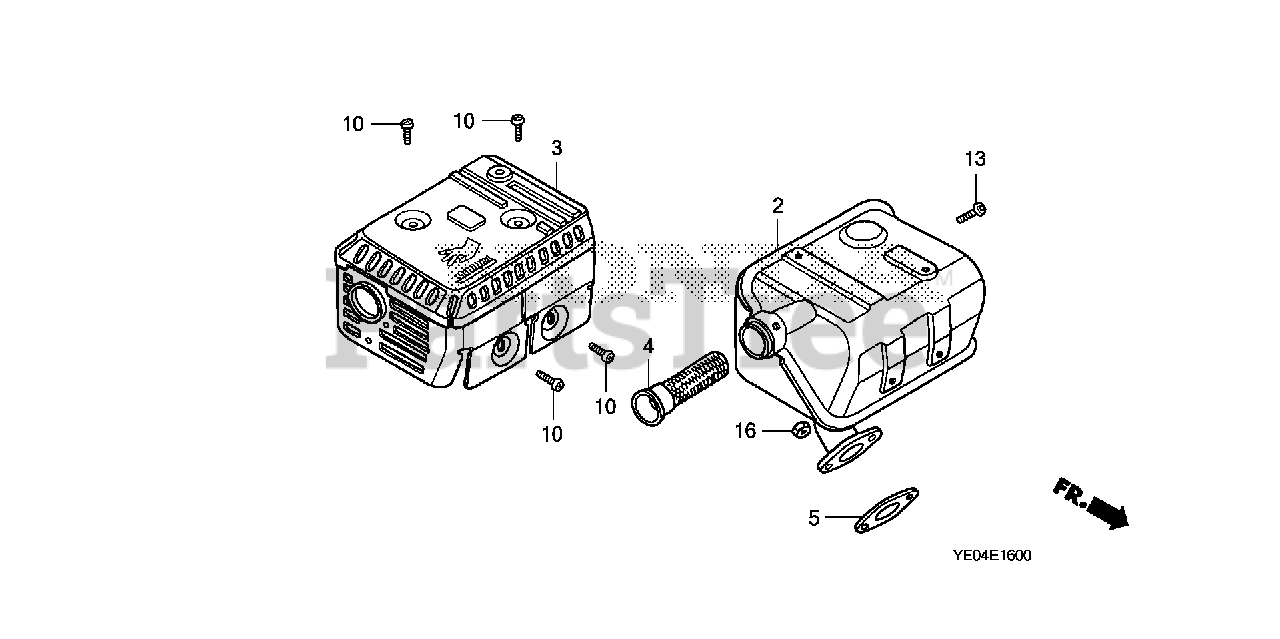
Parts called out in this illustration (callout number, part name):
2	MUFFLER
2	MUFFLER (ARRESTER)
3	PROTECTOR, MUFFLER (STD)
4	ARRESTER, SPARK
5	GASKET, MUFFLER
10	SCREW, TAPPING (5X8)
13	SCREW, TAPPING (4X6) (TO INSTALL OPTIONAL SPARK ARRESTER)
16	NUT, HEX. (8MM)
